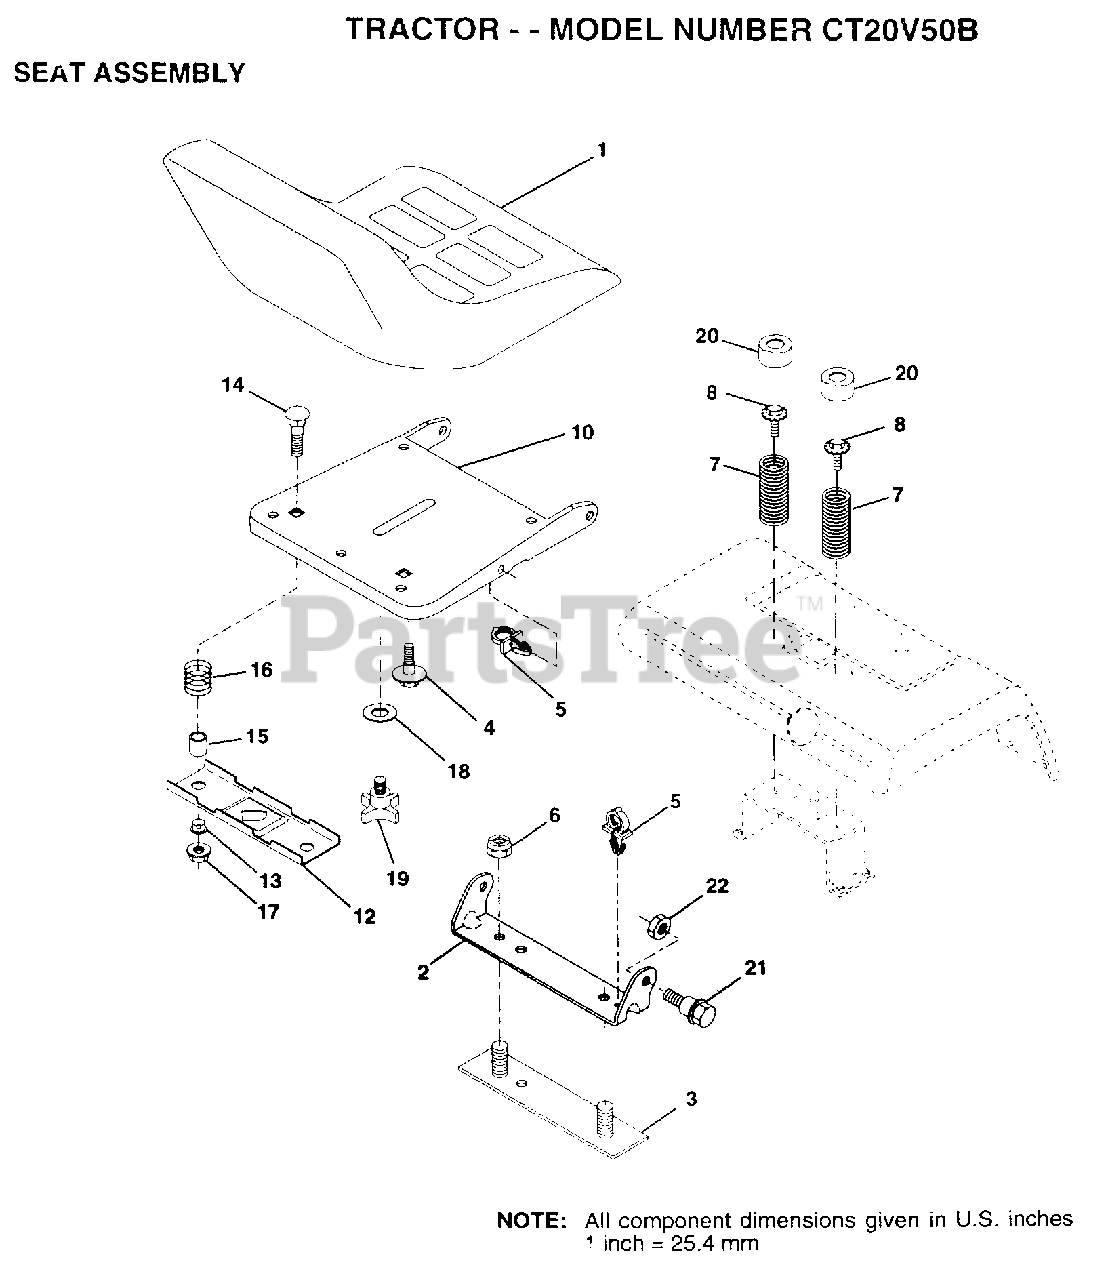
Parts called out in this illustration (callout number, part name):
2	BRACKET PVT SEAT
3	STRAP ASM FENDER
4	"BOLT,SHOULDER"
5	CLIP.PUSH-IN.HING
7	SPRING COMPRESSIO
8	BOLT.5/16-18.UNC
12	BRKT SWITCH
13	BUSHING
15	SPACER SPLIT
16	SPRING COMPRESSED
18	WASHER
19	"KNOB 1/2"" YT"
20	CAP SPRING
21	"BOLT,SHOULDER"
